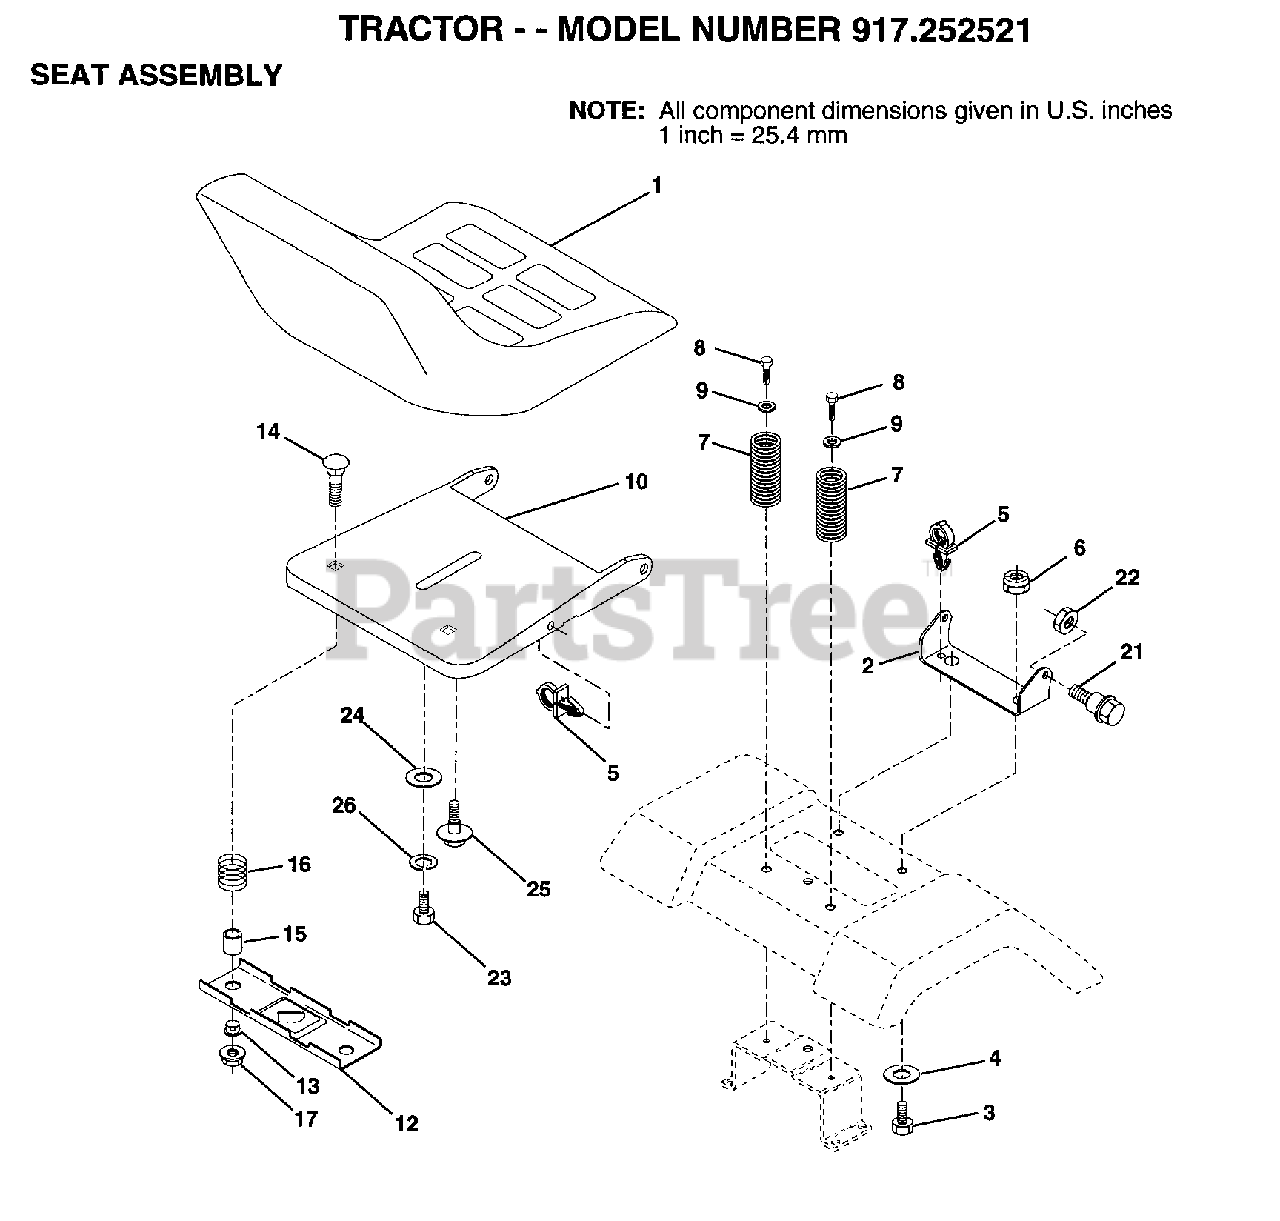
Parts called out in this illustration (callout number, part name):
2	BRACKET PVT SEAT
4	WASHER PM
5	CLIP.PUSH-IN.HING
7	SPRING COMPRESSIO
8	SCREW GTV
9	WASHER
12	BRKT SWITCH
13	BUSHING
15	SPLIT SPACER
16	SPRING
21	BOLT.SHLD.5/16-18
23	BOLT
24	WASHER
25	"BOLT,SHOULDER"
